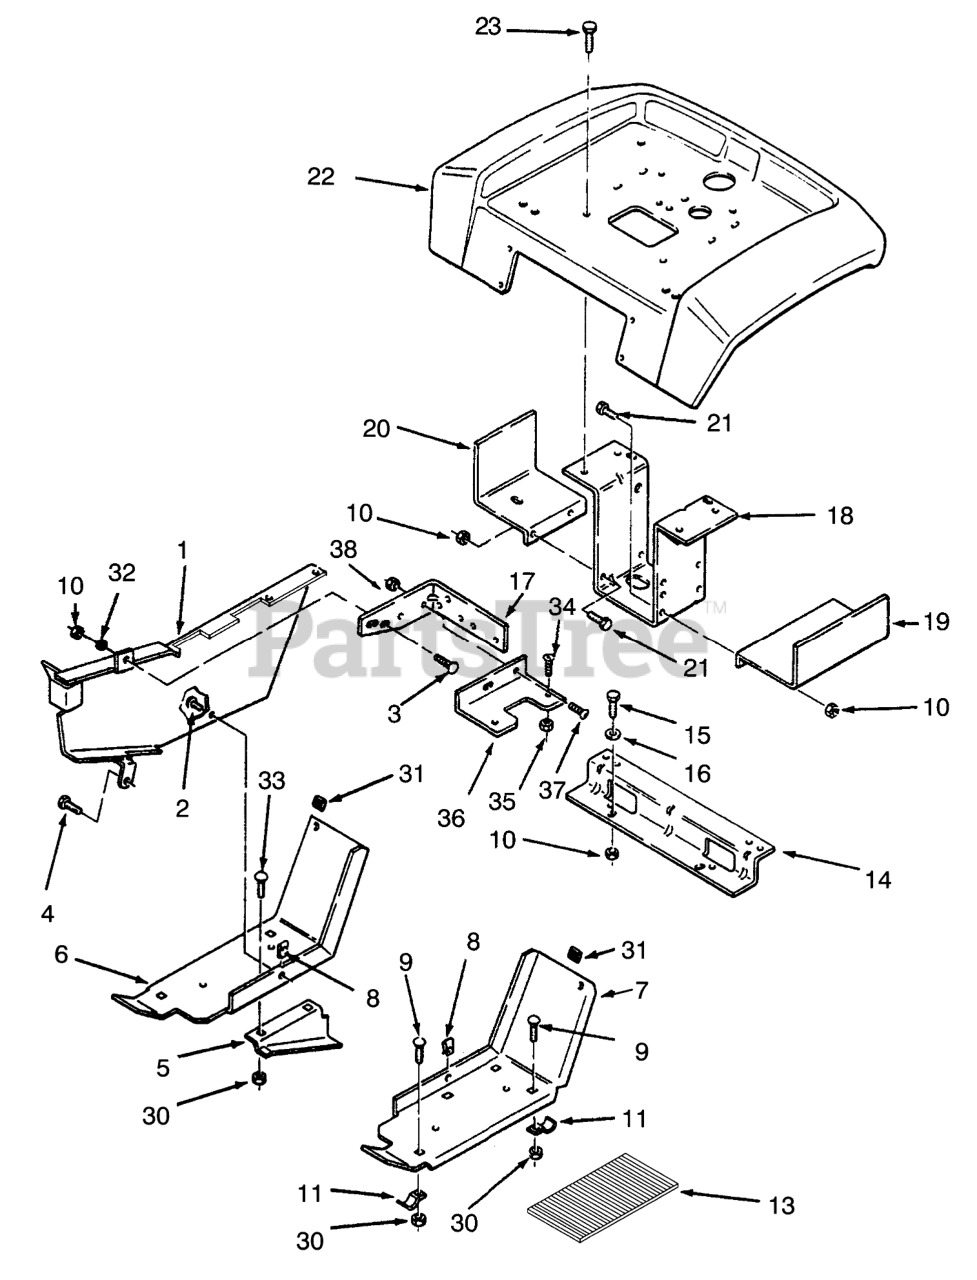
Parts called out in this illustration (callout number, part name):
1	Belt Guard
2	SCREW-PPH
3	BOLT-CARR
4	Bolt
5	GUID-LOWER BLTR
6	Footrest-RH
7	FOOTREST LH R
9	BOLT-CARR
10	NUT-LOCK, NI
11	BRACKET
13	PAD FOOTREST
14	BRACKET-FENDER B
15	SCREW-HH
16	WASHER-PLAIN
17	BRACKET-BELTB
18	Bracket-Fender
19	Fuel Tank Support LH
20	Support-FueITank RH
21	SCREW-HH
22	Fender
23	Bolt
30	NUT-LOCK, NI
31	BUMPER SJ5514 BLACK
32	NUT-PUSH
33	BOLT-CARR 5/16 SN
34	SCREW-PAN
35	Nut
36	BRKT-FUS HLDERB
37	SCREW-HH
38	NUT-LOCK, NI
